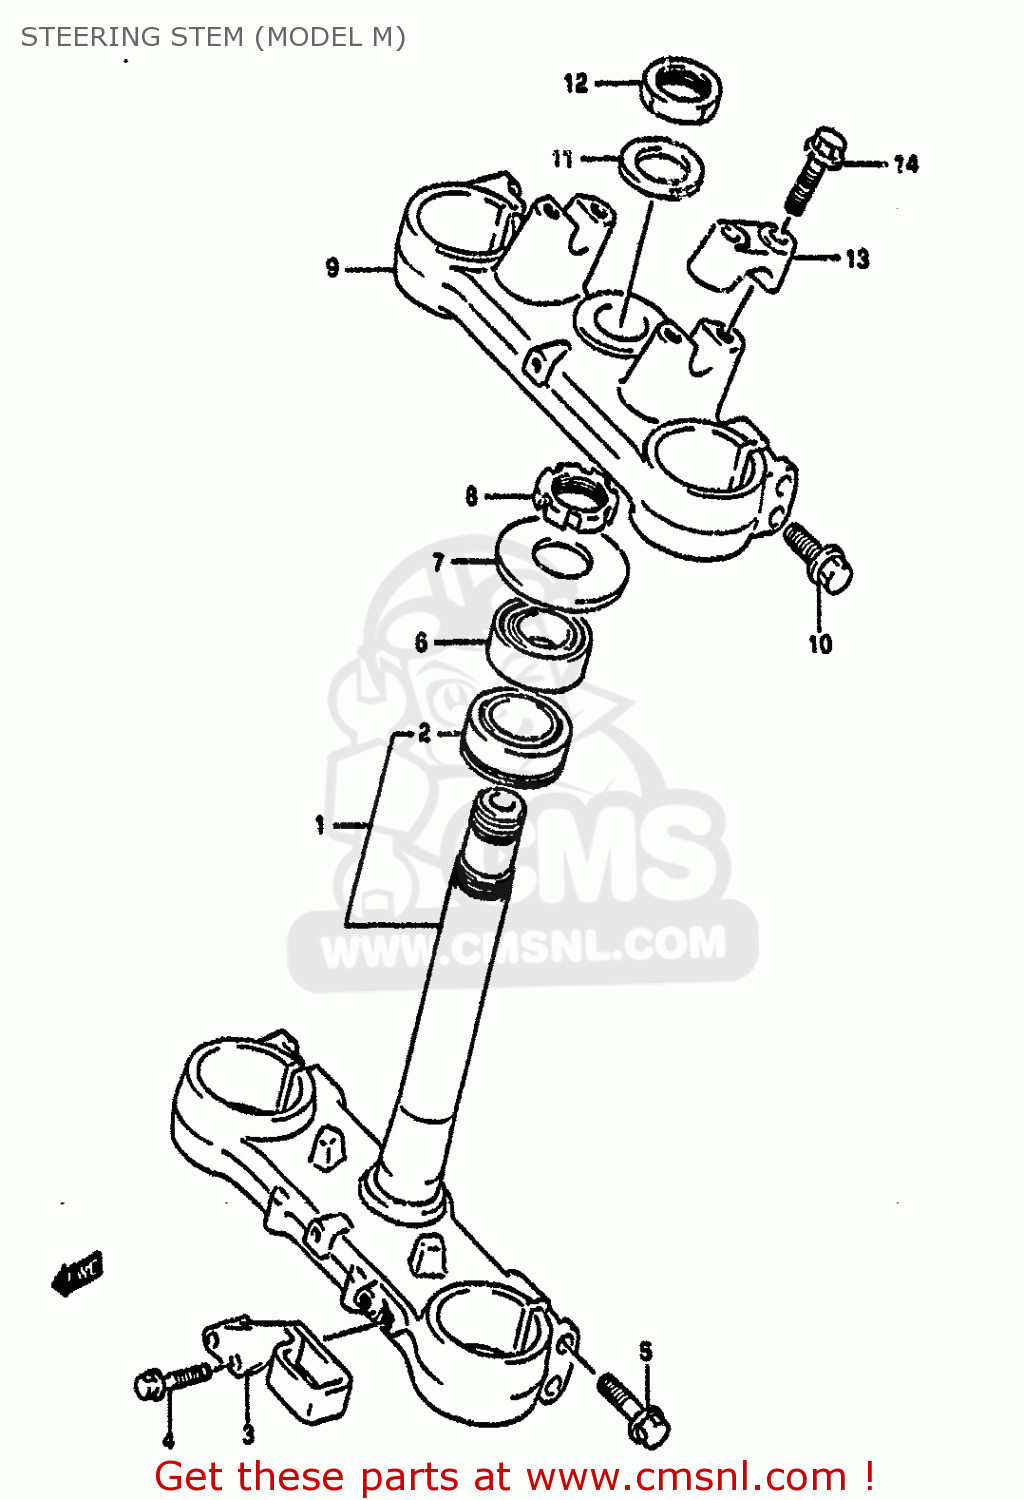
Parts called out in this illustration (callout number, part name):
1	STEM,STEERING
2	BEARING(30X52X16)
3	GUIDE,HOSE
4	BOLT,GUIDE
5	BOLT,STEM 8X45
6	BEARING
7	SEAL,STEERING,UPPER DUST
8	NUT,STEERING
9	HEAD,STEERING STEM
10	BOLT,STEM 8X45
11	WASHER,STEM HEAD
12	NUT,STEM HEAD
13	HOLDER,HANDLEBAR
14	BOLT,HANDLE HOLDER(8X35)
